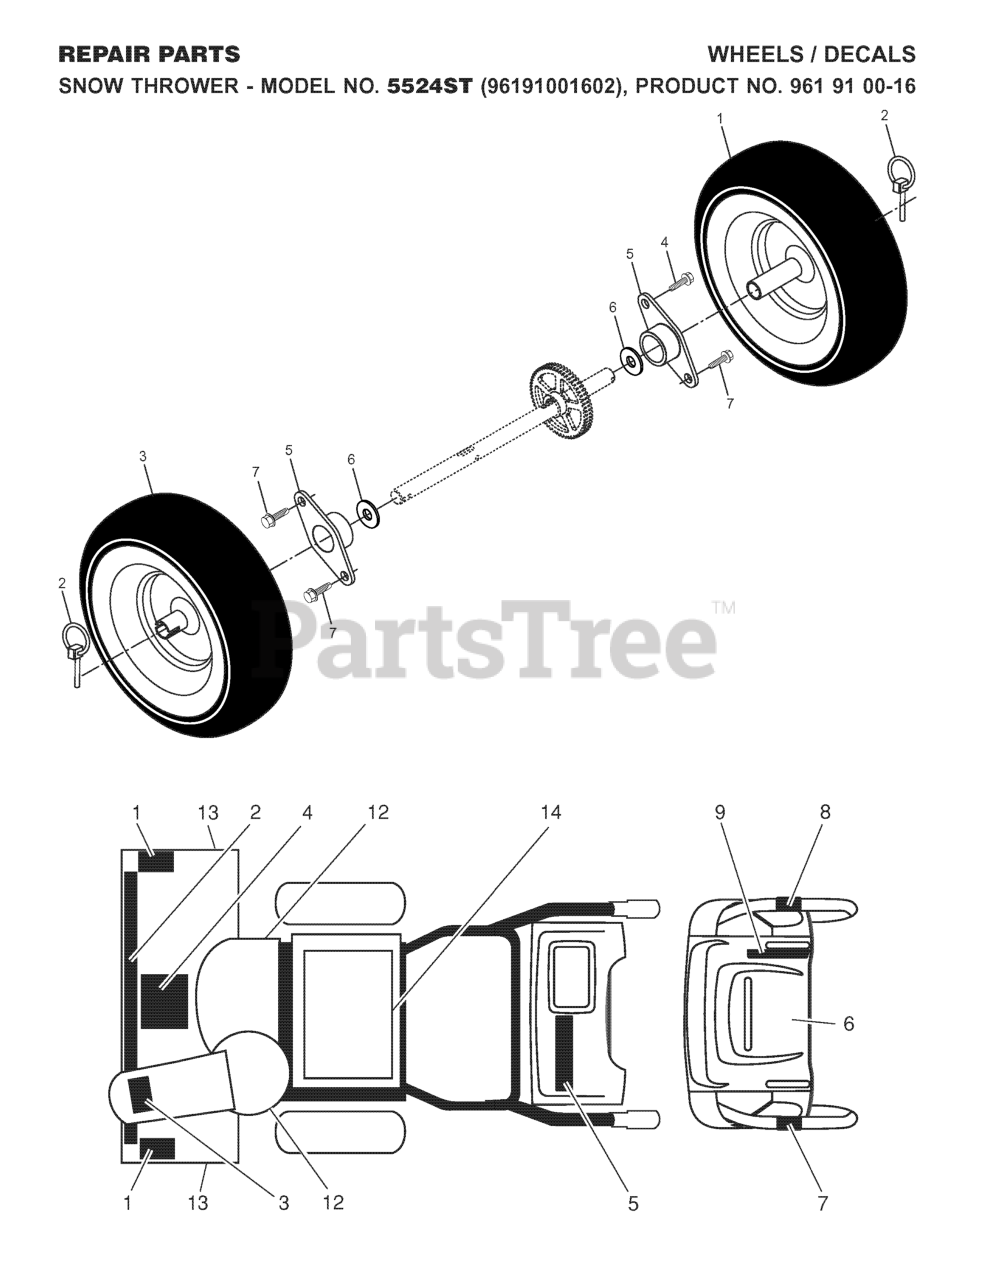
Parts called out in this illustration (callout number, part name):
1	DECAL.AUGER.SAFETY.
1	WHEEL.ASM.LT.16"GRY.XTRAC
2	PIN KLIK, 1/4
3	WHEEL.ASM.RT.16".GRAY.XTRAC
3	DECAL.CHUTE.SAFETY.
4	DECAL.AUGER."
5	BEARING, AXLE
6	DECAL.CONSOLE.INSTRUCTION
6	WASHER TRUST 1"
12	DECAL.BELT.GUARD.
13	DECAL, HUSQVARNA
14	DECAL.FENDER
